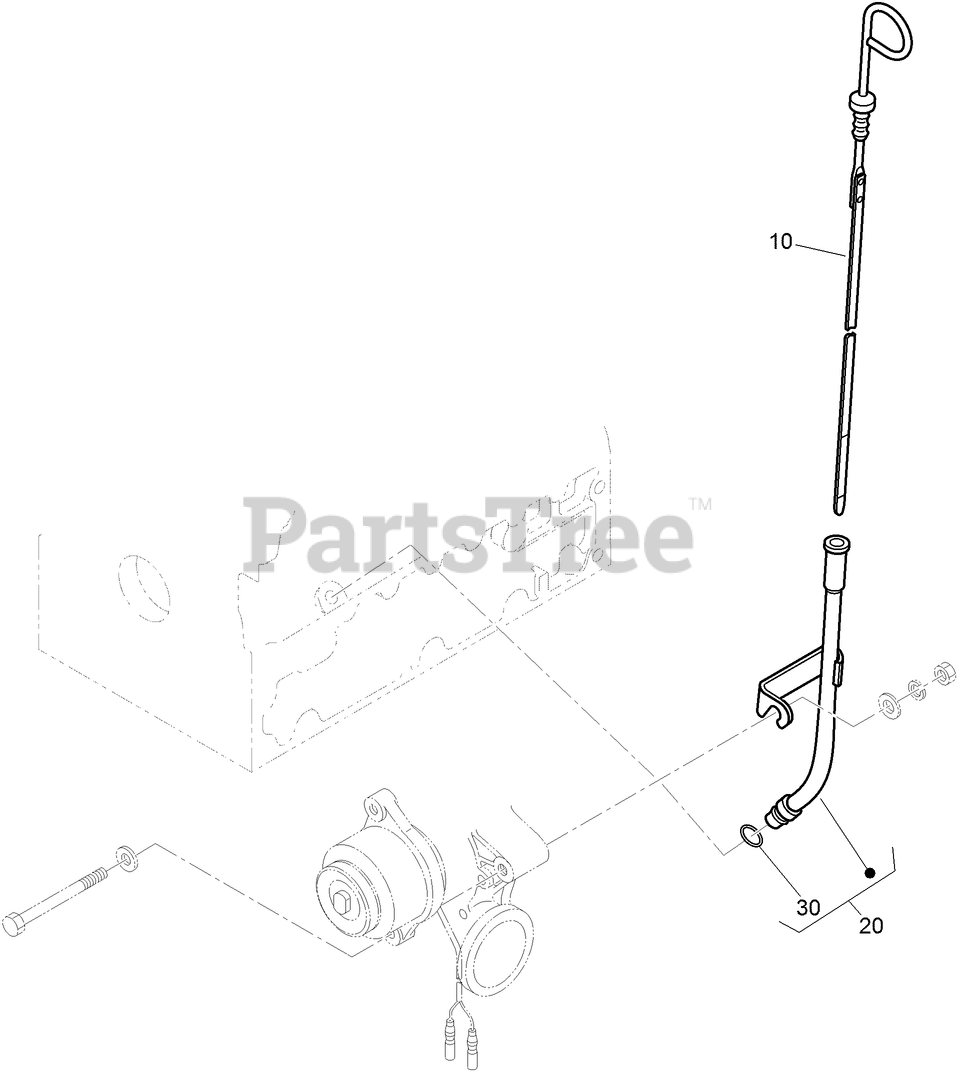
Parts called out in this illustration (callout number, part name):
10	GAUGE-OIL
20	OIL GAUGE GUIDE ASM
30	O-RING
